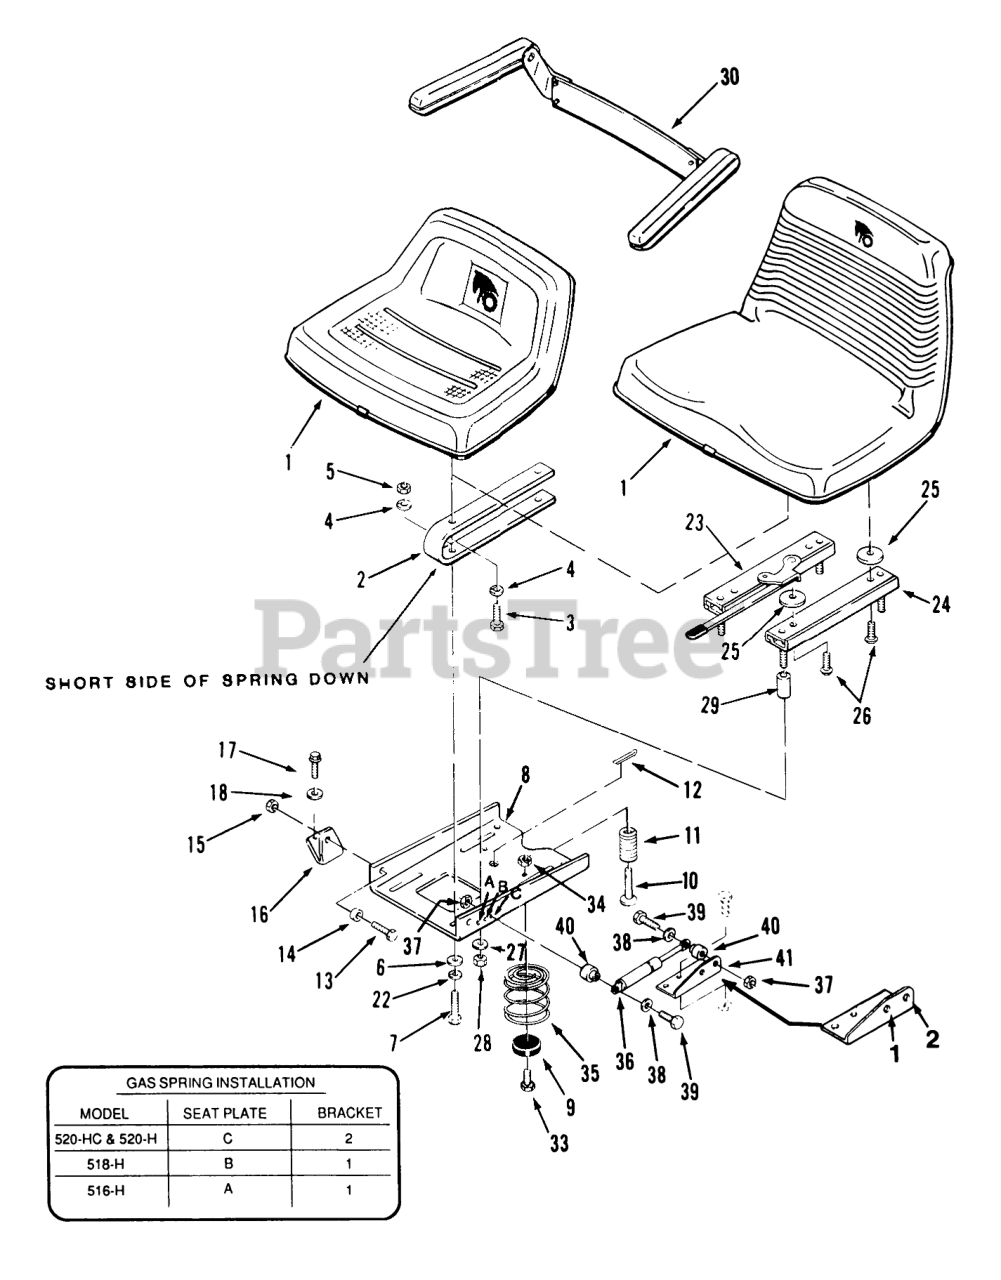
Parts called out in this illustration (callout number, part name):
1	Seat
2	Seat Spring
3	Bolt
4	Lockwasher
5	Nut
6	WASHER 5/16 SAE
7	HHCS
8	PLATE-SEAT PIVOT B
9	BUMPER
11	SPRING-SEAT SWITCH
12	Cotter Pin
13	HHCS
14	BUSHING
15	Nut
16	Bracket-Pivot RH
16	BRACKET-PIVOT L.H B
17	Bolt
23	Adjuster-Seat
24	ADJUSTER-R.H. SEAT
25	SPACER-NYLON
26	Screw
27	Collar
28	Nut
29	SPACER
30	KIT-ARMREST
33	Bolt
34	Nut
35	SPRING-SEAT NYLON
35	SPRING
36	GAS SPRING
37	Nut
39	Bolt
40	SPACER
41	BRACKET-CYLINDER R
